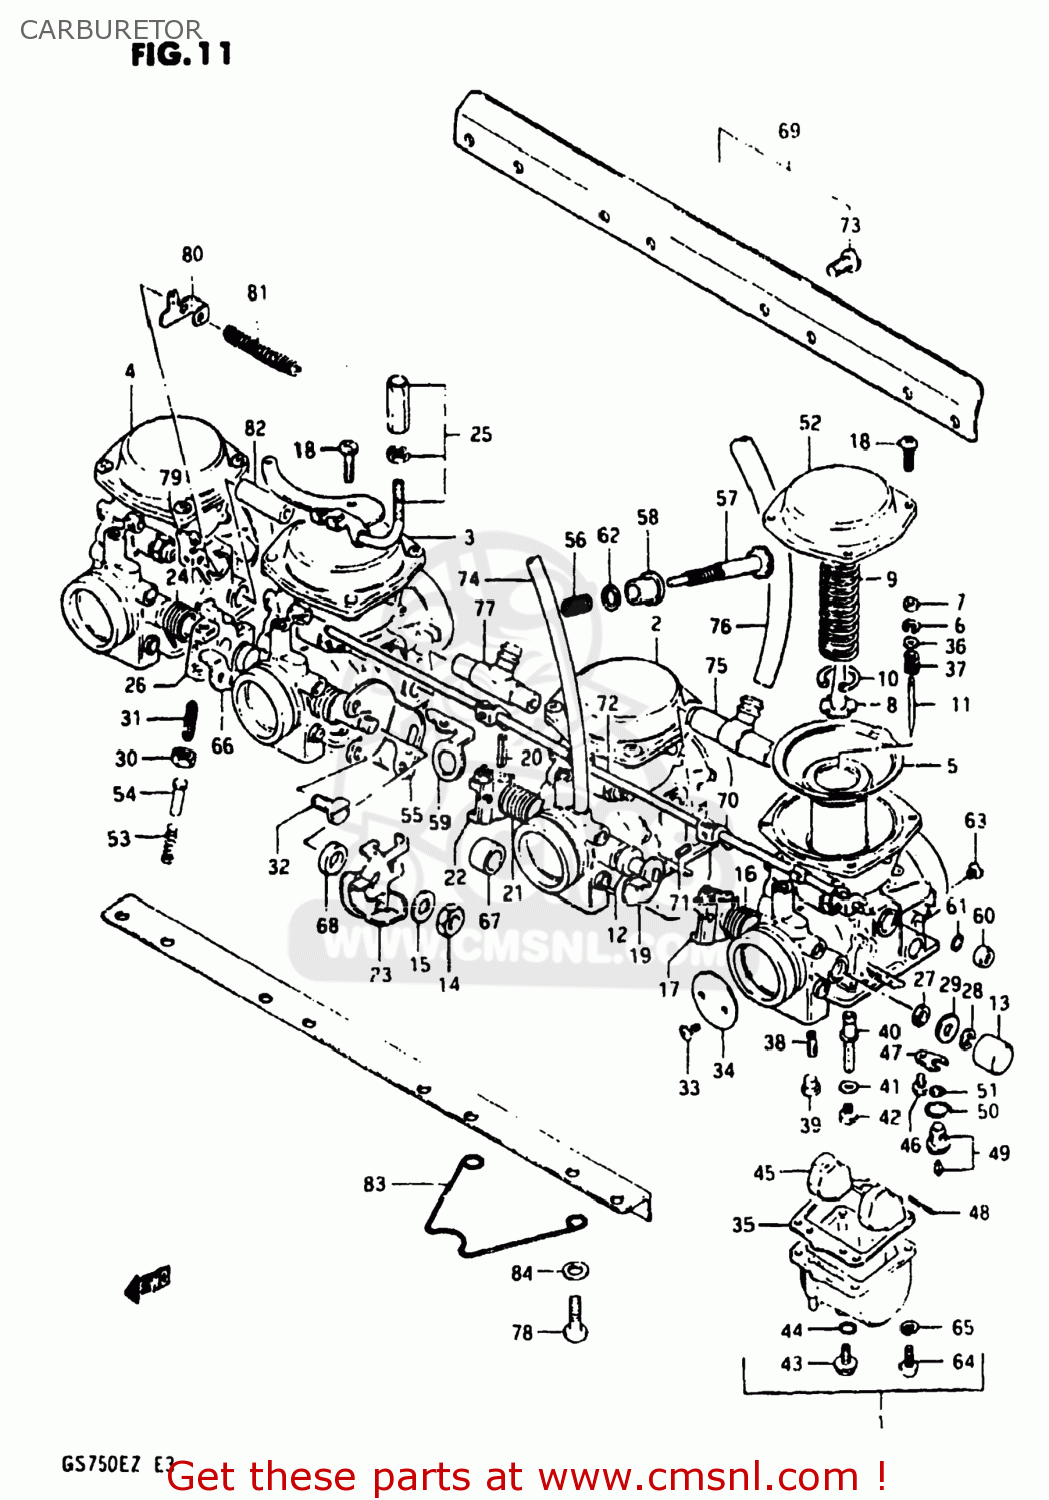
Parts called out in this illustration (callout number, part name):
1	CARBURETOR ASSEMBLY
2	CARBURETOR ASSEMBLY
3	CARBURETOR ASSEMBLY
4	CARBURETOR ASSEMBLY
5	DIAPHRAGM
6	CLIP,NEEDLE
7	RING
8	HOLDER,GUIDE
9	SPRING
10	E RING
11	NEEDLE JET
12	GASKET
13	CAP
14	NUT
15	WASHER
16	SPRING,THROTTLE SHAFT
17	SHAFT,THROTTLE
18	SCREW
19	SHAFT,THROTTLE
20	PIN,THROTTLE SHAFT
21	SPRING,THROTTLE SHAFT
22	LEVER,THROTTLE SHAFT
23	LEVER ASSEMBLY,THROTTLE
24	SPRING,THROTTLE SHAFT
25	BRACKET,THROTTLE CABLE
26	SHAFT,THROTTLE
27	SEAL
28	E RING
29	GASKET,THROTTLE SHAFT (NAS)
30	NUT
31	SCREW
32	SCREW
33	SCREW
34	VALVE,THROTTLE
35	GASKET,FLOAT CHAMBER (NAS)
36	WASHER
37	SPRING
38	JET,PILOT(42.5)
39	PLUG,NEEDLE JET
40	JET,NEEDLE
41	WASHER,NEEDLE NOZZLE
42	JET,MAIN(112.5)
43	PLUG,DRAIN
44	GASKET (NAS)
45	FLOAT
46	SCREW 4X6
47	PLATE,NEEDLE VALVE FITING
48	PIN,FLOAT
49	VALVE ASSEMBLY,NEEDLE
50	O-RING,NEEDLE VALVE
51	FILTER
52	COVER,DIAPHRAGM
53	SPRING,THROTTLE SCREW
54	PIN,THROTTLE LEVER
55	BRACKET,THROTTLE ADJUST
56	SPRING
57	SCREW
58	BUSH
59	BRACKET,THROTTLE ADJUST
60	CAP,STARTER VALVE
61	O RING
62	WASHER
63	JET,AIR
64	SCREW
65	LOCK WASHER
66	SHAFT,THROTTLE
67	RING
68	RING
69	CARBURETOR ASSEMBLY
70	LEVER
71	SCREW
72	SHAFT,STARTER
73	SCREW
74	HOSE
75	NIPPLE,CARBURETOR
76	HOSE,CARBURETOR
77	NIPPLE
78	SCREW 6X12
79	LEVER,CHOKE CABLE
80	PLATE,CHOKE CABLE
81	SPRING,CHOKE CABLE
82	NIPPLE
83	CLIP
84	WASHER
